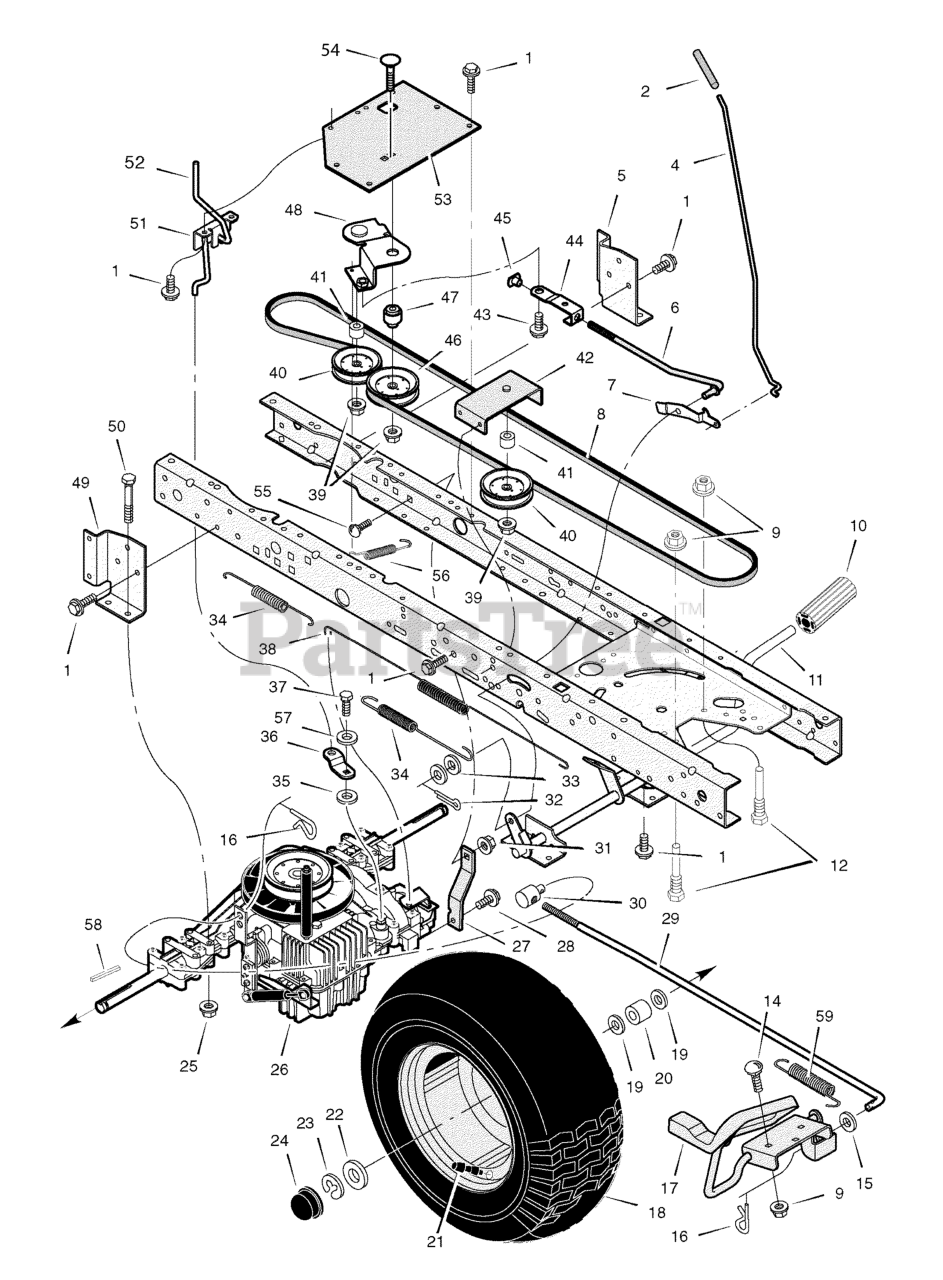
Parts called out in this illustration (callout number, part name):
2	Grip, Parking Brake
4	Rod, Parking Brake
5	Bracket, Left Transaxle
6	Rod, Clutch
7	Latch, Parking Brake
8	V--Belt, Drive
9	Nut, Flange
10	Pedal, Brake/Clutch
11	Assembly, Brake Pedal
12	Screw, Guide
14	Bolt, Carriage
16	Pin, Hair
17	Pedal Assembly, Hydro
18	Wheel & Tire Ass'y, Rear
21	Stem, Valve
23	E--Ring
24	Cap, Hub
25	Nut, Centerlock
26	Transaxle, Peerless Hydro **
27	Strap, Torque
29	Rod, Control
30	Nut, Adjusting
31	Nut, Centerlock
32	Pin, Cotter
34	Spring, Extension
36	Arm, Disconnect
37	Capscrew
38	Spring, Brake
39	Locknut, Flange
40	Pulley, Idler
42	Bracket, Idler Assembly
43	Bolt, Shoulder
44	Link, Clutch
45	Nut, Tee
46	Pulley, Idler
47	Bushing, Pivot
48	Arm Assembly, Idler
49	Bracket, Right Transaxle
50	Bolt, Hex
51	Bracket, Dump Valve
52	Rod, Roll Release
53	Bracket, Idler Pivot
54	Bolt, Carriage
55	Bolt, Carriage
56	Spring, Clutch
58	Key, Square 3/16"
